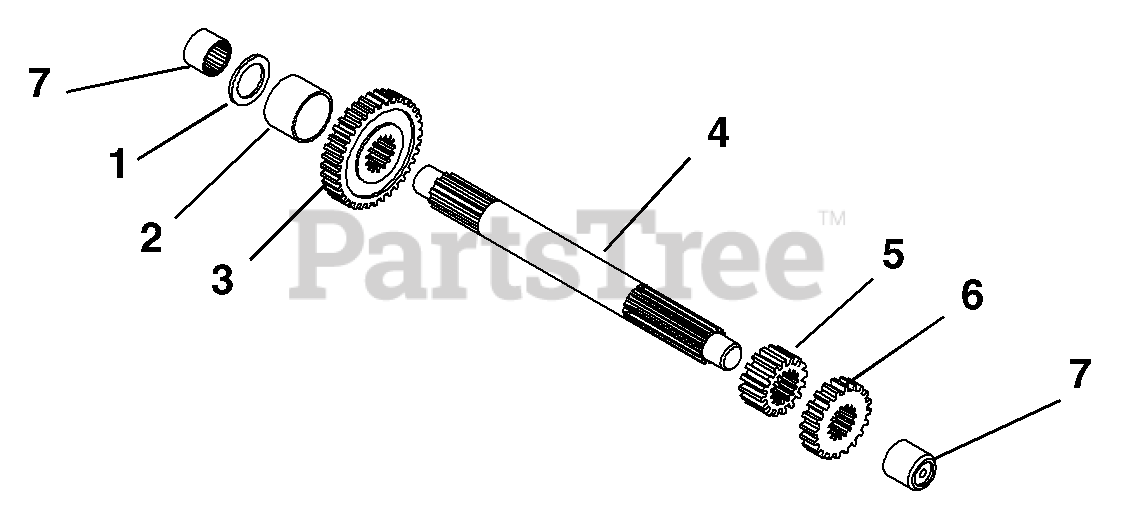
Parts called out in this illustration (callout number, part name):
1	Washer-Thrust .06 x 1.15 x .093
2	Bushing-Sleeve Steel 1.03 x 1.13 x .46
3	Gear
4	Shaft, Splined
5	Gear, 10 Diametral Pitch 16 Teeth x .75
6	Gear, 10 Diametral Pitch 20 Teeth x .60
7	Bearing-Needle .63 x .81 x .75
